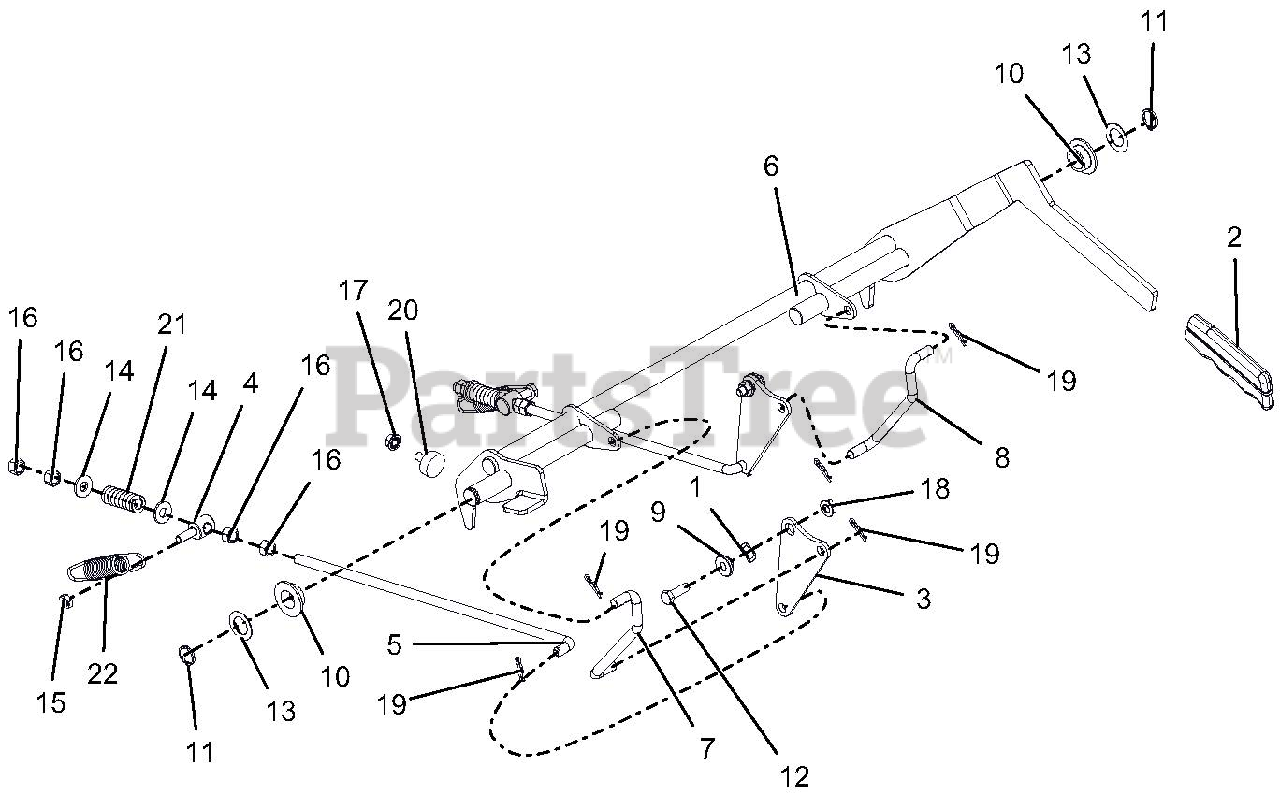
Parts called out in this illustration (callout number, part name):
1	WAVE WASHER .531X.781X.125 FH
2	GRIP, PARKING BRAKE
3	PLATE, BRAKE PIVOT
4	TRUNNION, .31-18
5	ROD, BRAKE ADJ.
6	WLDMT, PARKING BRAKE LEVER
7	LINKAGE, RH BRAKE ACTUATING
8	LINKAGE, LH BRAKE ACTUATING
9	BSHG, FLG .32X.500.344X.880
10	BSHG, FLANGE .762 X 1.48 X .44 NYLON
11	RG-RTNG-EXT .750x.078
12	BLT-HEX .31-18X1.00 GR5 YWZC
13	WSHR-HDND-THRST
14	WSHR-FL-STL.38X.875X.083 YWZC
15	@NUT-LK-CTR-JAM .31-18 YWZC
16	NUT-HEX .38-16 YWZC
17	@NUT-SPNLK-FLG .312-18 YWZC
18	NUT, LK-TOP-FLG .312-18 YWZC
19	PIN-HAIR, ENDRIES #25 YWZC
20	BUMPER, RUBBER
21	SPRG, COMPRESSION
22	SPRG, TENSION .105 X .850 X 4.880
